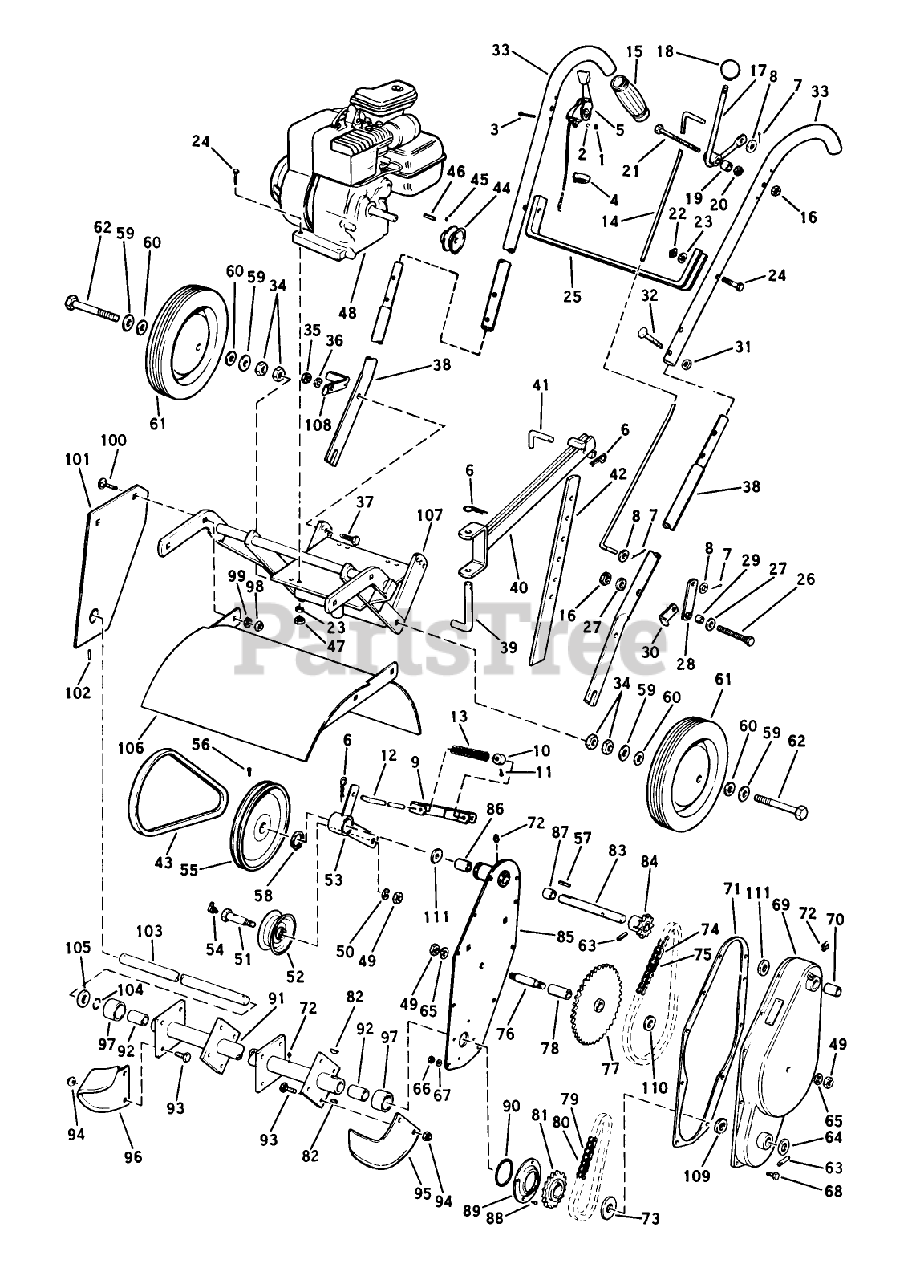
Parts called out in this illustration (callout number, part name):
2	Lockwasher
3	Machine Screw #8-32 x 1-1/2 Lg.
4	Cable Clip
5	Throttle Control Assembly
9	Spring Bracket Assembly
11	Set Screw
12	Engine 8 H.P.
13	SRV BULLT 437B
17	Control Lever Assembly
28	Shifting Lever
32	Square Nut 5/16-18
34	Hex Jam Nut 1/2-13
35	LOCKNUT
37	Capscrew 3/8-16 x 1-1/4 Lg.
38	Handle Bar Tube Assembly
40	Beam Assembly
41	Selector Pin
42	Depth Bar
48	Engine (B S)
52	Idler Pulley
53	Idler Arm Assembly
56	Set Screw
60	Rubber Washer
61	Wheel Assembly 10 x 1.75
62	Hex Head Capscrew 1/2-13 NC x 4 Lg.
63	Roll Pin
65	Lockwasher, Shakeproof
67	WASHER-LOCK
69	Cover Assembly
72	Grease Fitting
73	Thrust Washer
74	Chain #41-1/2 Pitch, 55 Links
76	Intermediate Shaft
77	Sprocket Cluster Assy
78	Bushing
79	Extension-Chute
82	Woodruff Key
84	Input Sprocket and Hub Assv.
85	Back Plate Assembly
88	Self Tapping Screw #8-32 x 1/4 Lg.
89	Oil Seal Retainer
91	Rotor Tube Assembly
96	Tine LH
98	Nut-Hex
99	WASHER, LOCK
100	Carriage Bolt 3/8-16 x 1 Lg.
101	Side Plate Assembly
102	Roll Pin
103	Rotor Shaft
106	Hood Assembly
